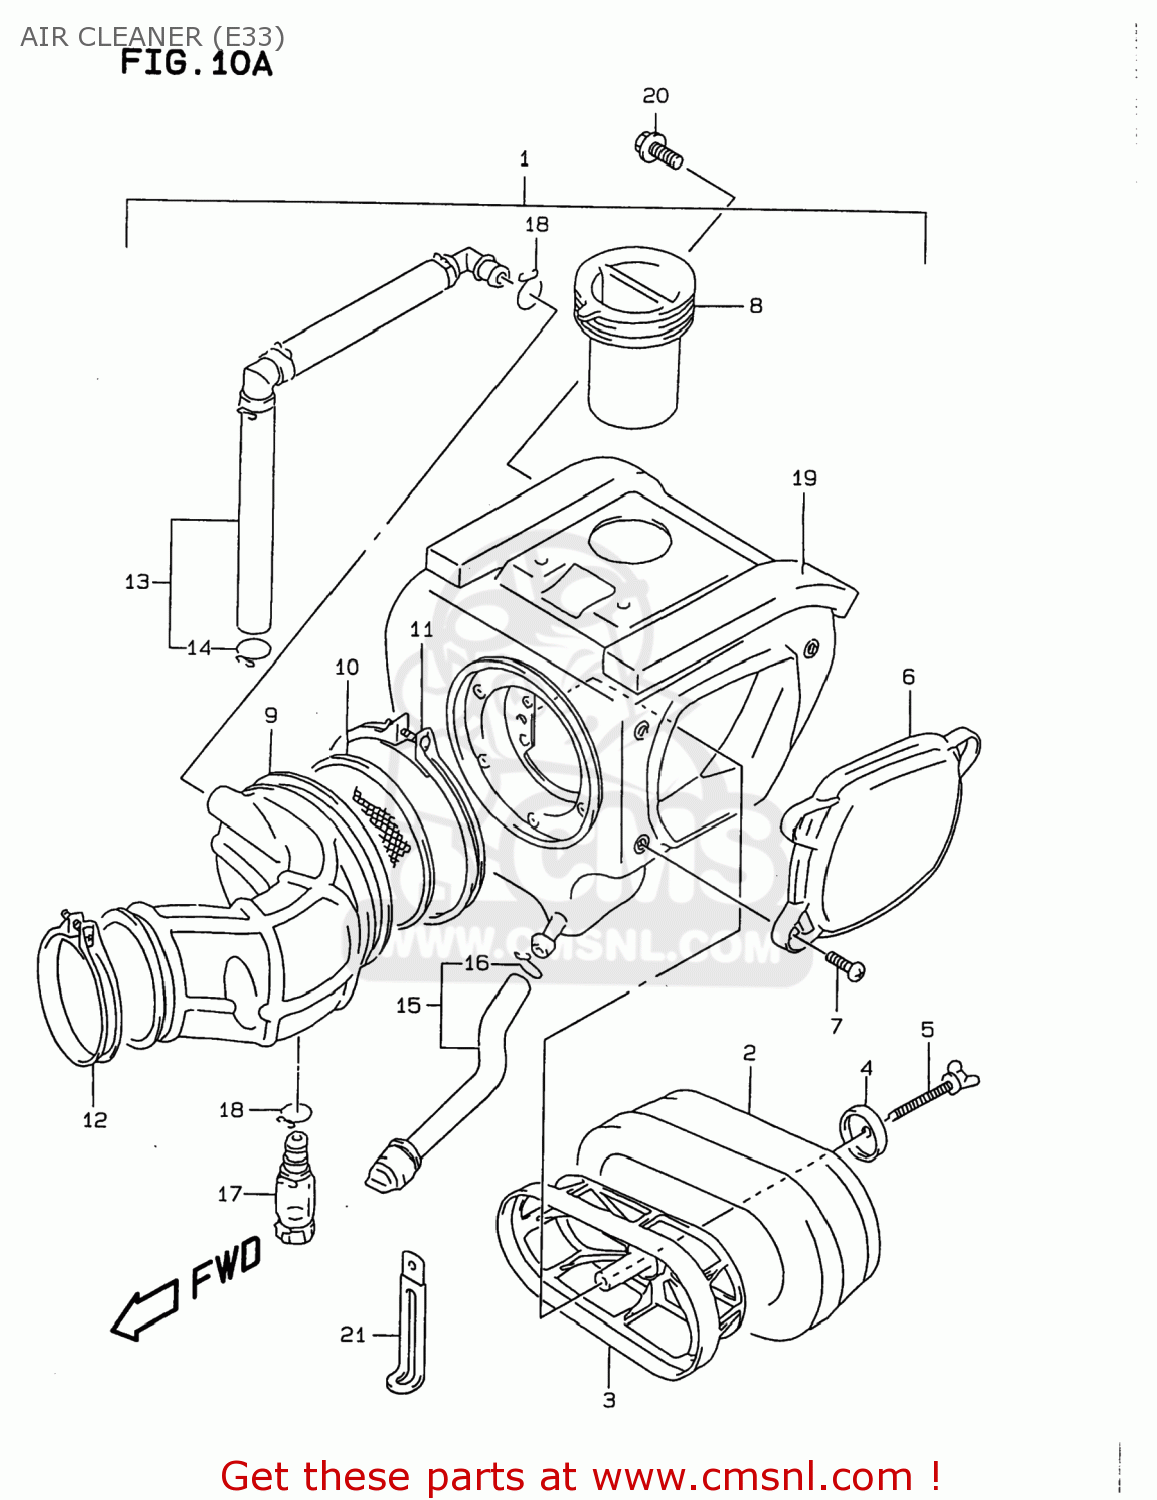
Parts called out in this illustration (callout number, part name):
1	CLEANER ASSY,AIR
2	FILTER
3	HOLDER,FILTER
4	WASHER,AIR CLEANER
5	BOLT,WING
6	CAP,AIR CLEANER
7	SCREW
8	TUBE,INLET
9	TUBE,OUTLET
10	TRAP,FRAME
11	CLAMP,OUTLET TUBE
12	CLAMP
13	TUBE,BREATHER
14	CLIP
15	TUBE,DRAIN A
16	CLIP
17	TUBE,DRAIN
18	CLIP
19	CUSHION
20	BOLT
21	CLAMP(L:80)
